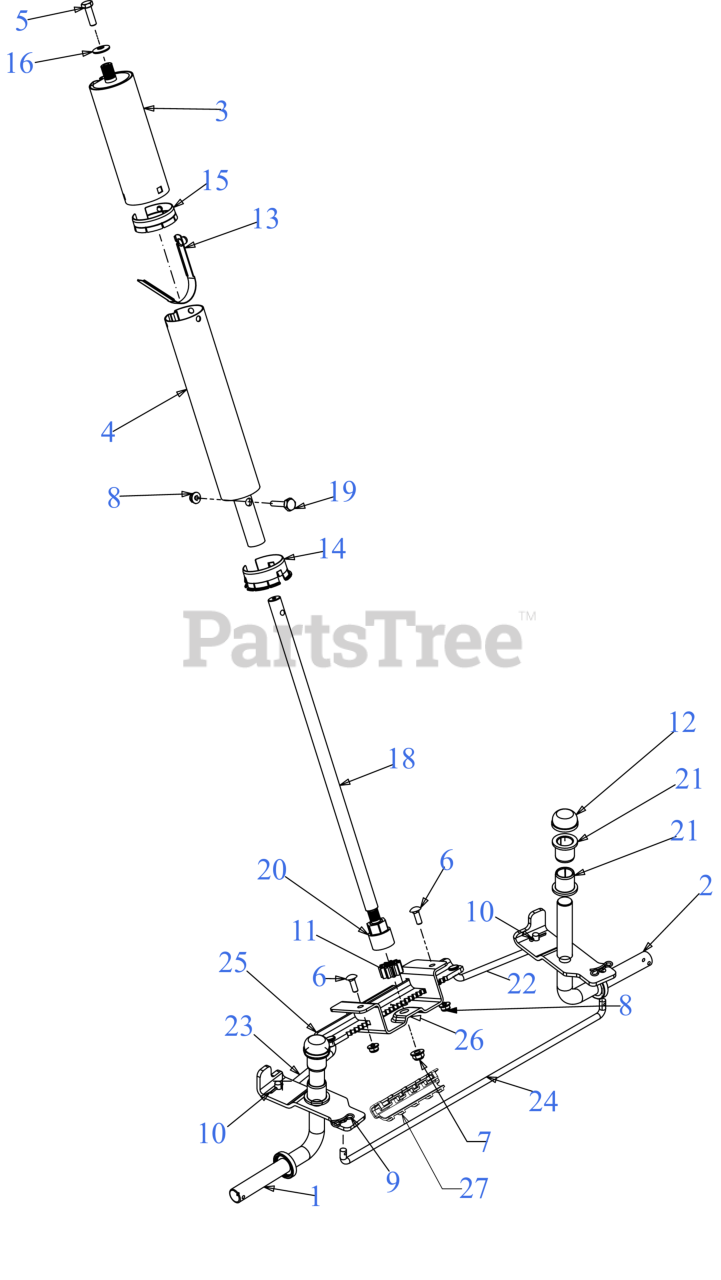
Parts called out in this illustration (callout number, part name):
3	UPPER TUBE ASSEMBLY
4	LOWER TUBE ASSEMBLY
5	SCREW 5/16-18 x 1.00 GR5
6	SCREW 1/4-20 x .75 GR5
7	FLANGE LOCK NUT 5/16-18
8	FLANGE LOCK NUT
9	BOW TIE COTTER PIN 1/4-5/16
10	COTTER PIN-3/32 DIA x .75
11	STEERING PINION GEAR
13	SNAP BUTTON
14	LOWER STEERING COLLAR
15	UPPER STEERING COLLAR
16	BELL WASHER .337 X.867 x .057
18	STEERING SHAFT
19	SHOULDER SCREW .375 x .148
20	FLANGE BEARING
21	FLANGE BEARING .760 ID
22	STEERING ROD (LH)
23	STEERING ROD (RH)
24	FRONT TIE ROD
25	RACK STEERING PLATE
26	LOWER STEERING BRACKET
27	RACK SUPPORT
